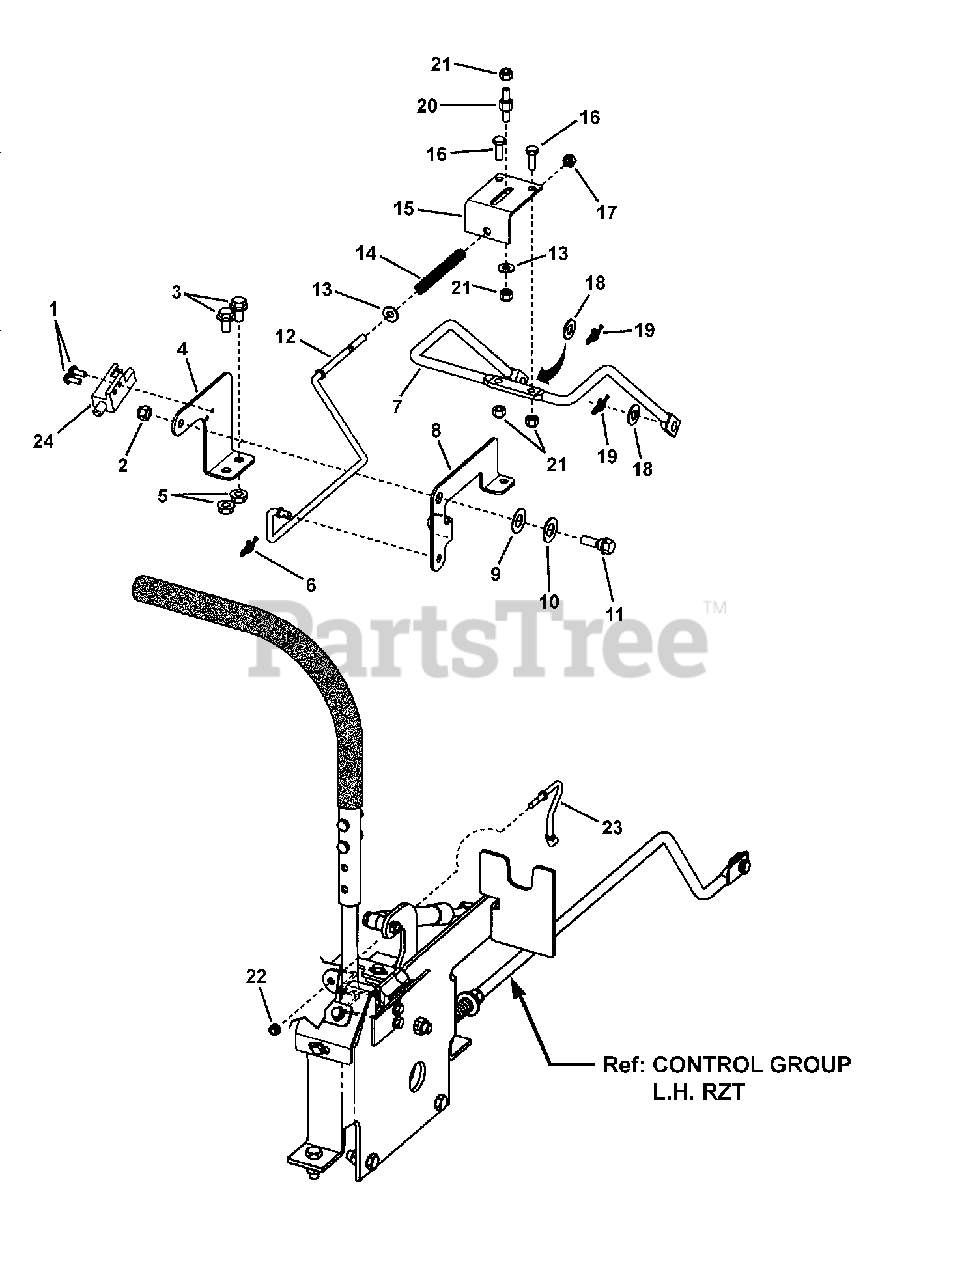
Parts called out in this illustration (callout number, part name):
1	SCREW, #10-24 x 1/2" Hex Washer Self-Tap (Torx)
2	NUT, 5/16-18 Hex Nyloc
3	BOLT, 5/16-18 x 5/8" Hex Flange Lock, GR 5
4	BRACKET, Park Brake, LH Lower
5	NUT, 5/16-18 Hex Flange Lock, GR 5
6	COTTER PIN, 3/8" Self-Locking
7	ROD, Park Brake
8	BRACKET, Park Brake, RH Lower
9	WASHER, 1/2 x .090 Flat
10	WASHER, .531 x 1.0 x .063 Flat
11	SHOULDER BOLT, 5/16-18 x 1"
12	ROD, Park Brake (1/4-20 thread)
13	WASHER, .28 x .63 x .06 Flat, GR 5
14	SPRING, Compression
15	BRACKET, Park Brake
16	SCREW, 1/4-20 x 3/4" Hex Head Cap, GR 5
17	NUT, 1/4-20 Hex Top Lock, GR B
18	WASHER, 3/8" Flat SAE
19	COTTER PIN, 1/2 Self Locking, YZ
20	ROD, Hanger (1/4-20 both ends)
21	NUT, 1/4-20 Hex Nyloc YZ
22	NUT, 10-24 Hex Nyloc
23	HOOK, Park Brake
24	SWITCH- DPDT
